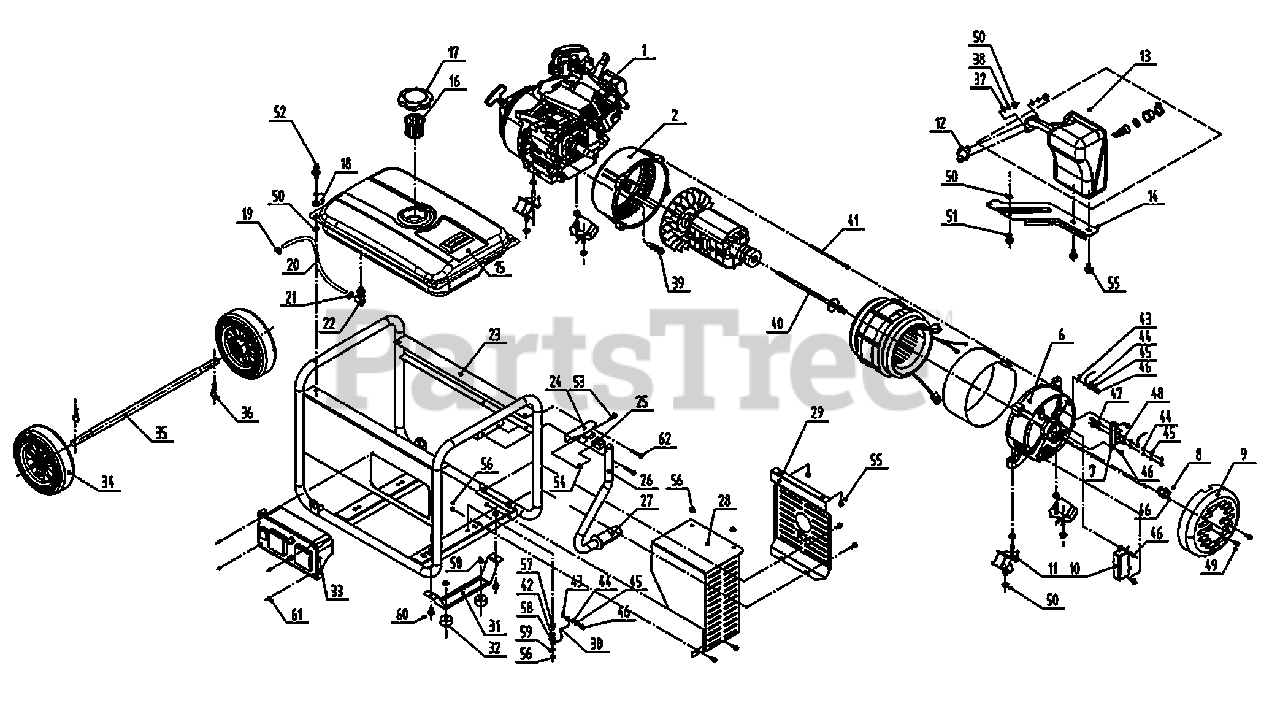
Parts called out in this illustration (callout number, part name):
1	ENGINE 208CC AUS 50HZ
2	ADAPTOR CASTING, ENG/ALT 3250W
3	ROTOR
4	STATOR
5	ALTERNATOR GUARD BOARD
6	REAR BEARING CARRIER 190
7	REAR WIRING FRAME ORANGE
8	ASSEMBLY BRUSH PORTABLE
9	COVER, ALTERNATOR
11	VIB MOUNT 35 X 15 X M8-1.25
12	GASKET MUFFLER 163/208CC
14	BRACKET MUFFLER MNT 163/208CC
15	FUEL TANK SUBASSEMBLY
16	FILTER, FUEL
17	FUEL TANK CAP
18	RUBBER MOUNT 8 ID X 5 HGT
19	CLAMP HOSE BAND SPRING .38
20	FUEL HOSE,4.5 ID,8.5 OD,160 LG
21	CLAMP HOSE BAND SPRING .38
22	VALVE FUEL SHUTOFF 4GAL TANK
23	ASSY FRAME GP3250 1-PIECE
24	BRACKET, HANDLE 3.25KW PORTABLE
25	SPACER HANDLE PLASTIC 3.25KW
26	HANDLE 3250W GP
27	GRIP HANDLE 3250W GP
28	HEAT SHLD EXHST FRNT 163/208CC
29	HEAT SHIELD,EXHAUST SIDE
30	WIRE, GROUND
31	BRACKET FOOT 3.25KW PORTBLE
32	VIB MNT 38.1 X 25.4 X M8-1.25
33	PANEL ASSY., CONTROL
34	WHEEL, 8" NEVER-FLAT 3.25KW
35	AXLE, SOLID 3.25KW UP PORTABLE
36	COTTER HAIRPIN 2.56 X .80
37	FLAT WASHER
38	SPRING WASHER
39	SCREW HHFC M8-1.25 X 25 W/M10
40	SCREW HHFC 5/16-24 X 8.26
41	SCREW HHC M6-1.0 X 130
42	SPRING WASHER
43	EXTERNAL TOOTH LOCK WASHER
44	FLAT WASHER
45	SPRING WASHER
46	SCREW HHFC M5-0.8 X 16
47	SCREW HHC M5-0.8 X 20 G8.8
48	NUT HEX M5-0.8 G8 CLEAR ZINC
49	SCREW HHFC M5-0.8 X 12
50	FLANGE NUT M8
51	FLANGE BOLT M8X35
52	FLANGE BOLT M8X25 (WITH FLAT WASHER )
53	FLANGE BOLT M6X40
54	BLOCKING NUT M6
55	FLANGE BOLT M6X12
56	FLANGE NUT M6
57	FLANGE BOLT M6X14
58	FLAT WASHER
59	EXTERNAL TOOTH LOCK WASHER
60	FLANGE BOLT M8X16
61	CROSS RECESSED PAN HEAD TAPPING SCREWS ST4.2X12
62	FLANGE BOLT M8X40
